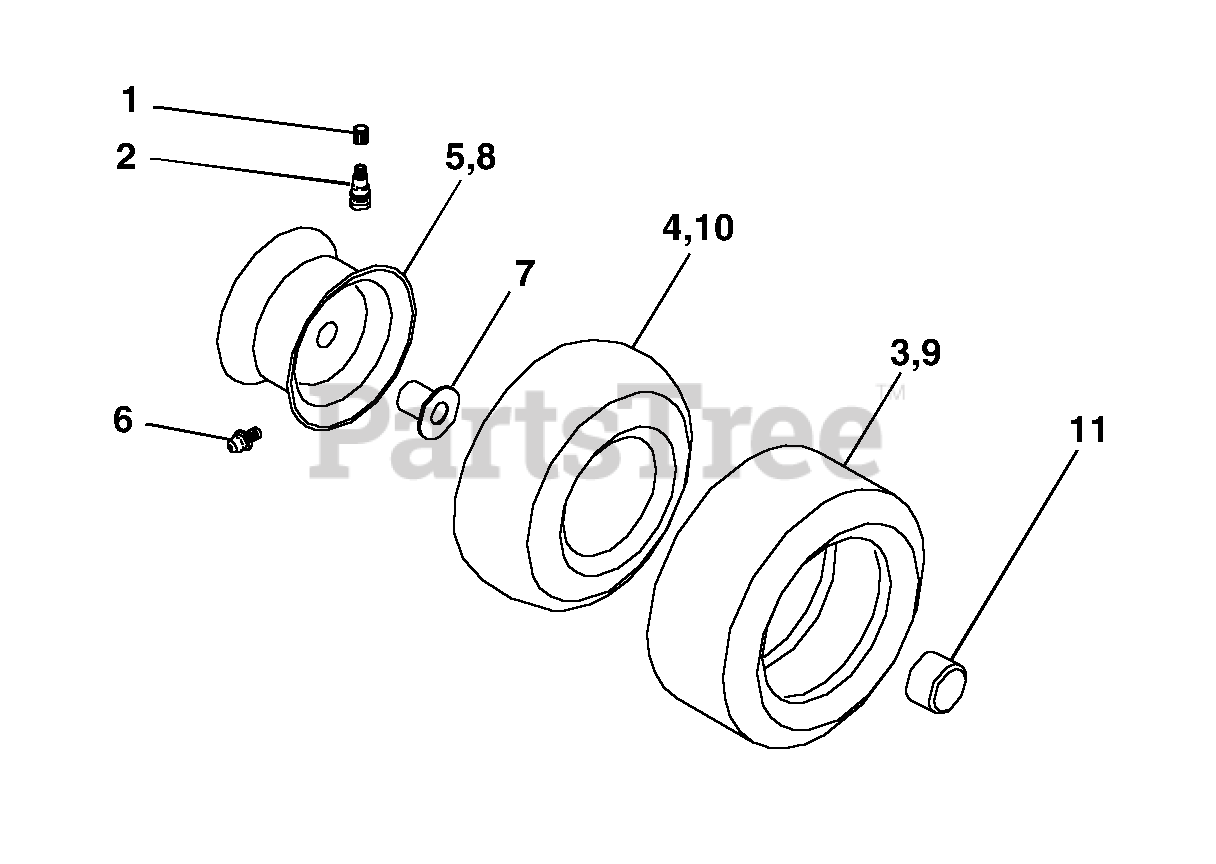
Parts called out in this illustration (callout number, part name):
1	Cap Valve Tire
2	Stem Valve
3	Tire F Ts 15 X 6 0 - 6 Service
4	Tube Front (Service Item Only)
5	Rim Asm 6"front Silver Service
6	Fitting Grease (Front Wheel Only)
7	Bearing Flange (Front Wheel Only)
8	Rim Asm 8"rear Silver Service
9	Tire R Ts 18x8 5-8 C Service
10	Tube Rear (Service Item Only)
11	Cap Axle Blk 1 50 X 1 00
